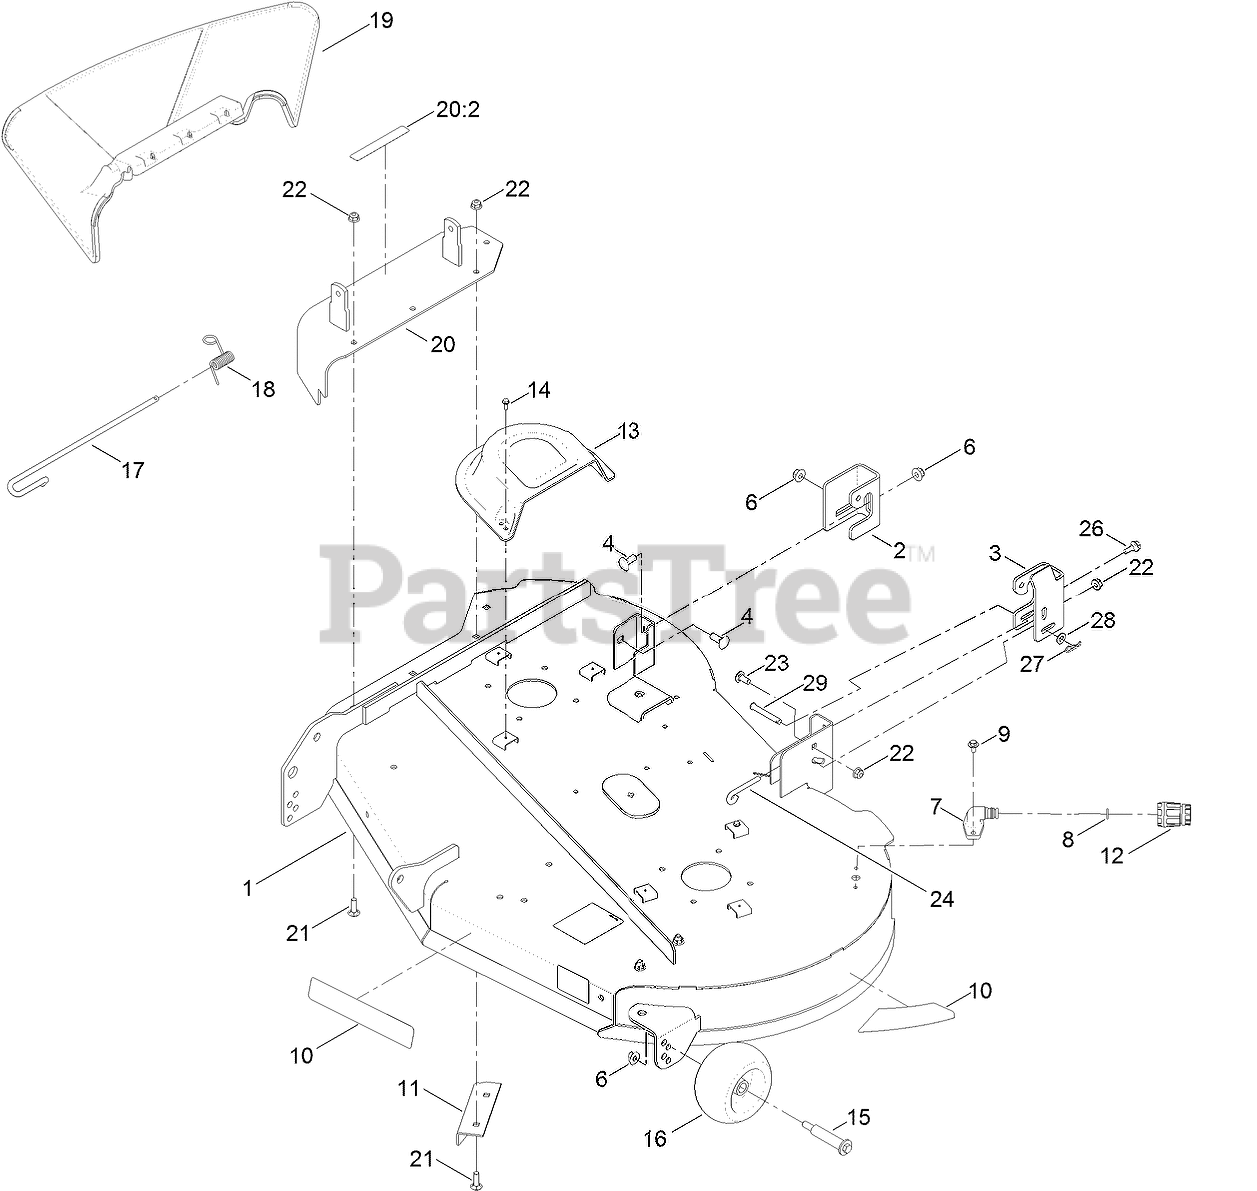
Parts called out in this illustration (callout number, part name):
1	42 IN DECK AND DECAL ASM
2	BRACKET-HANGER, RH
3	BRACKET-HANGER, LH
4	BOLT-CARR
6	NUT-HF, NI
7	FITTING-WASHOUT
8	O-RING
9	SCREW-HHFTF
10	DECAL-DECK
11	BAFFLE-CUTOFF
12	CONNECTOR-HOSE
13	COVER-BELT
14	SCREW-TAPTITE
15	BOLT-SHOULDER
16	ROLLER-SCALP, ANTI
17	PIN-CHUTE
18	SPRING-TORSION
19	DEFLECTOR-DISCHARGE
20	COVER ASM W/DECAL
20:2	DECAL-DANGER
21	SCREW-CARR
22	NUT-HF, NI
23	SCREW-CARR
24	ROD-LEVEL, DECK
26	SCREW-SHOULDER, HHF
27	PIN-COTTER
28	WASHER-PLAIN
29	PIN-CLEVIS
